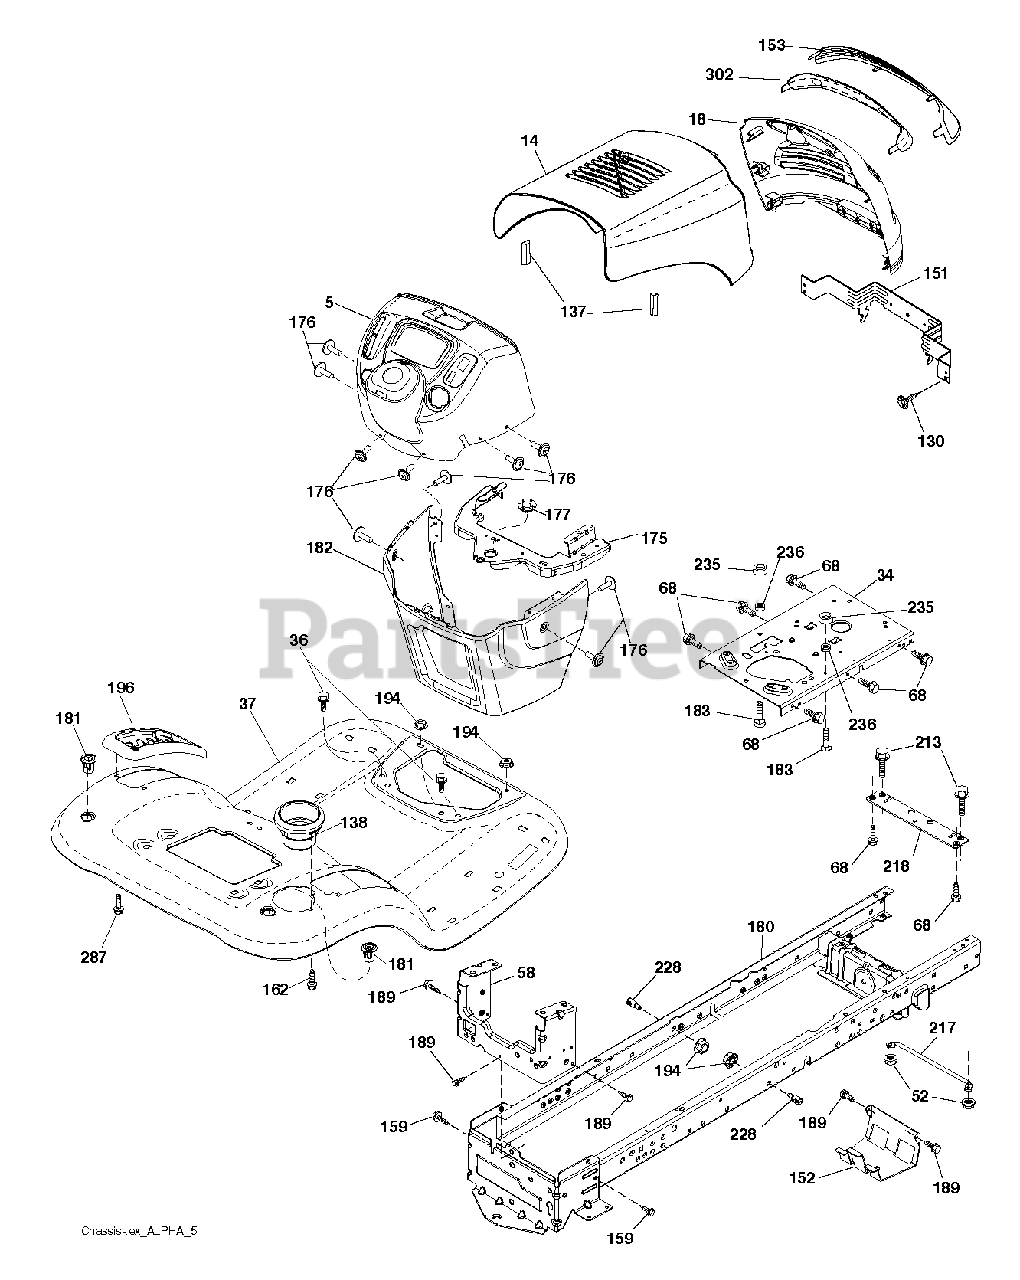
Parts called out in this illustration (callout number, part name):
5	DASH.P/L.TEX.CBL.CL.N/CHK.BLAC
14	HOOD.BLACK.ALPHA
18	GRILLE.ASM.ALPHA
34	PLATE.ENGINE.WELDED.CHASSIS
36	SCREW 5/16"
37	FENDER.TLT.FS.W/CPH.428
52	LOCKNUT
58	DRAWBAR UPPER 2PC SMALL FENDER
68	SCREW LT
130	SCREW.#10 X 0.750.BOS (2 2)
137	BUMPER.HOOD.LARGE.1.75"
138	CUPHOLDER.TL.TEX.BLACK
151	BRACKET.PIVOT.ALPHA.LT
152	SHIELD.BROWNING.W/TEX
153	LENS.ALPHA.BAR.LT
159	SCREW, 3/8-16X3/4
162	SCREW.HI-LO.CONSOLE
175	CROSSMEMBER.LT
176	SCREW.#10-24X5/8.RN.QU
177	BUSHING STEERING
180	CHASS.WLDMNT.TL.12GA/2P.48/54
181	SHIELD.DEFLECTOR.MOWER.42"BLAC
182	DASH.LOWER.LT.CCS
183	BOLT.5/16-18X1-1/4 FULL THD
189	SCREW
194	NUT LOCK HEX FLANGE 5/16-18
196	CONSOLE.ASM.DECKLFT.BL/RBT.TLT
213	BOLT
217	ROD.PIVOT.HOOD
218	X-PIECE.HOOD.STOP.NON/
228	STUD.FASTNER.W/ANTI-ROTATE
235	SPACER FENDER
236	NUT.CENTERLOCK.5/16-
287	SCREW 1/4X20
302	INSERT.ALPHA.REFLECTIVE.LT.
